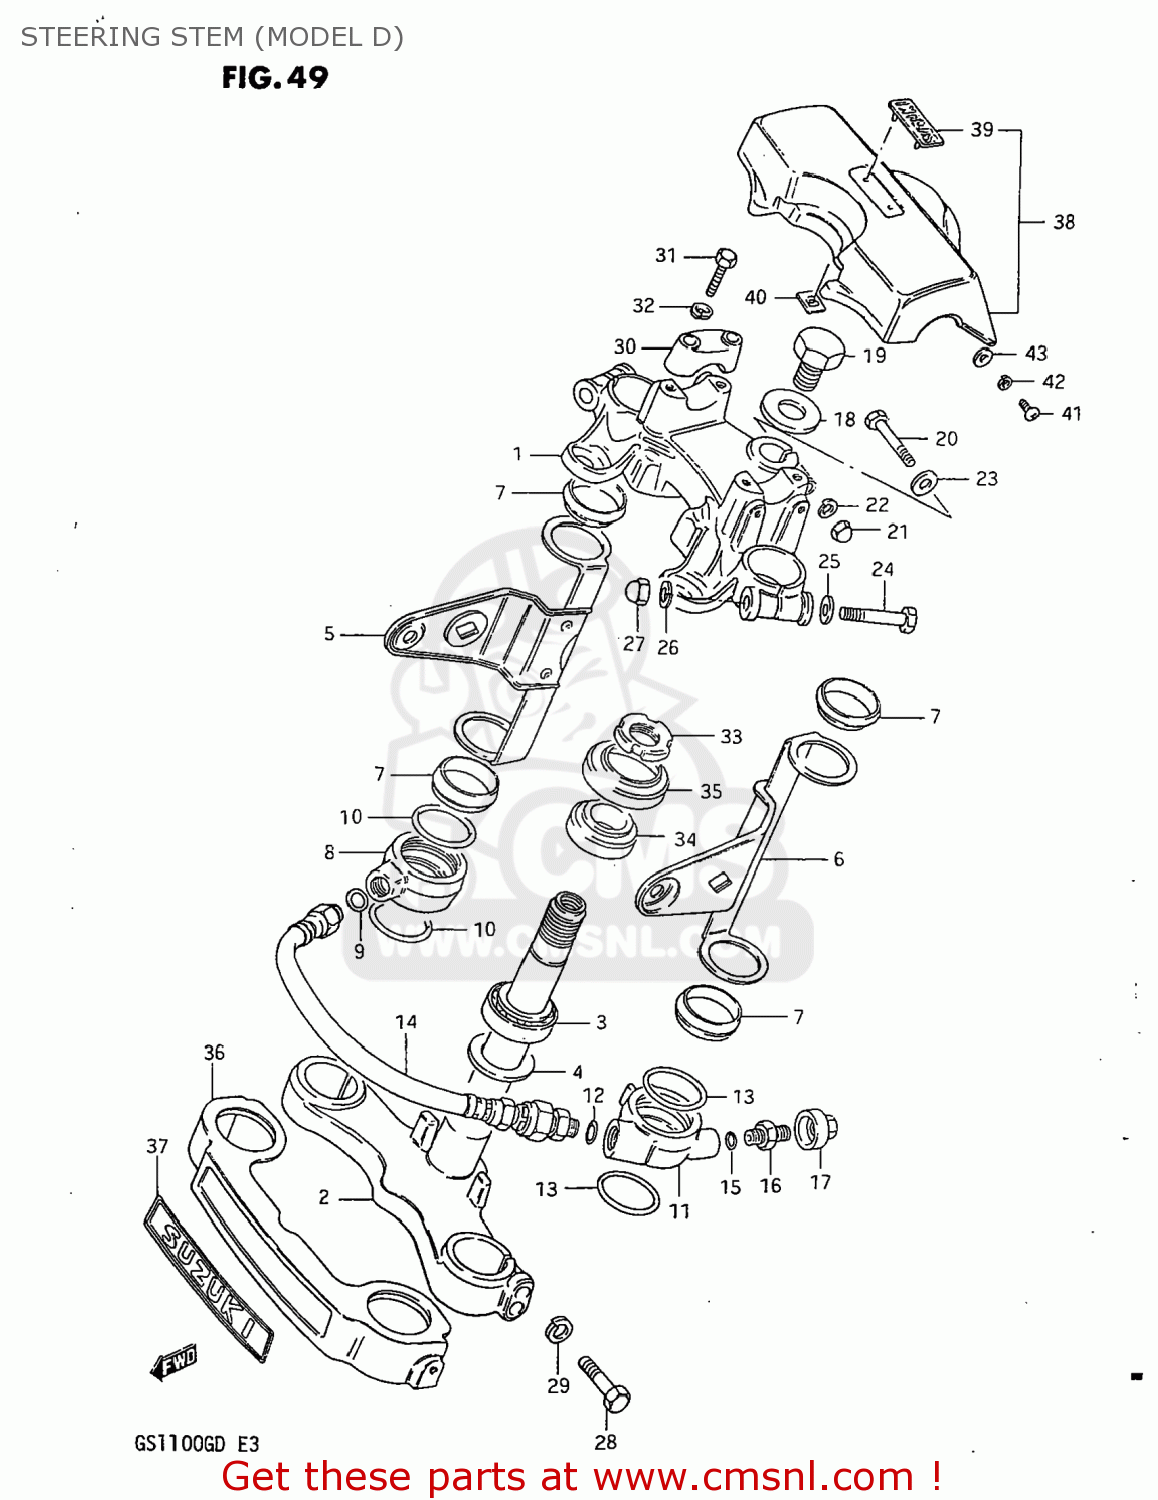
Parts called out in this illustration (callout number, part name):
1	HEAD,STEERING STEM
2	STEM,STEERING
3	BEARING
4	WASHER,THRUST
5	BRACKET,HEADLAMP,RIGHT
6	BRACKET,HEADLAMP,LEFT
7	CUSHION,HEADLAMP BRACKET
8	JOINT,AIR,RIGHT
9	O-RING
10	O RING
11	JOINT,AIR,LEFT
12	O-RING
13	O RING
14	HOSE
15	O-RING
16	VALVE,FRONT FORK AIR
17	CAP,FRONT FORK AIR VALVE
18	WASHER,STEERING STEM
19	NUT,STEM HEAD
20	BOLT 8X50
21	NUT
22	LOCK WASHER
23	WASHER
24	BOLT 10X55
25	WASHER
26	LOCK WASHER
27	NUT, LOWER LH
28	BOLT
29	LOCK WASHER
30	HOLDER,HANDLE(BLACK)
31	BOLT
32	LOCK WASHER
33	NUT,STEERING STEM
34	TAPER,ROLLER BEARING
35	DUST SEAL,STEERING UPR
36	COVER,FRONT FORK
37	EMBLEM,FRONT FORK COVER
38	PAD,HANDLEBAR
39	EMBLEM,HANDLE COVER PAD
40	NUT
41	SCREW
42	LOCK WASHER
43	WASHER
